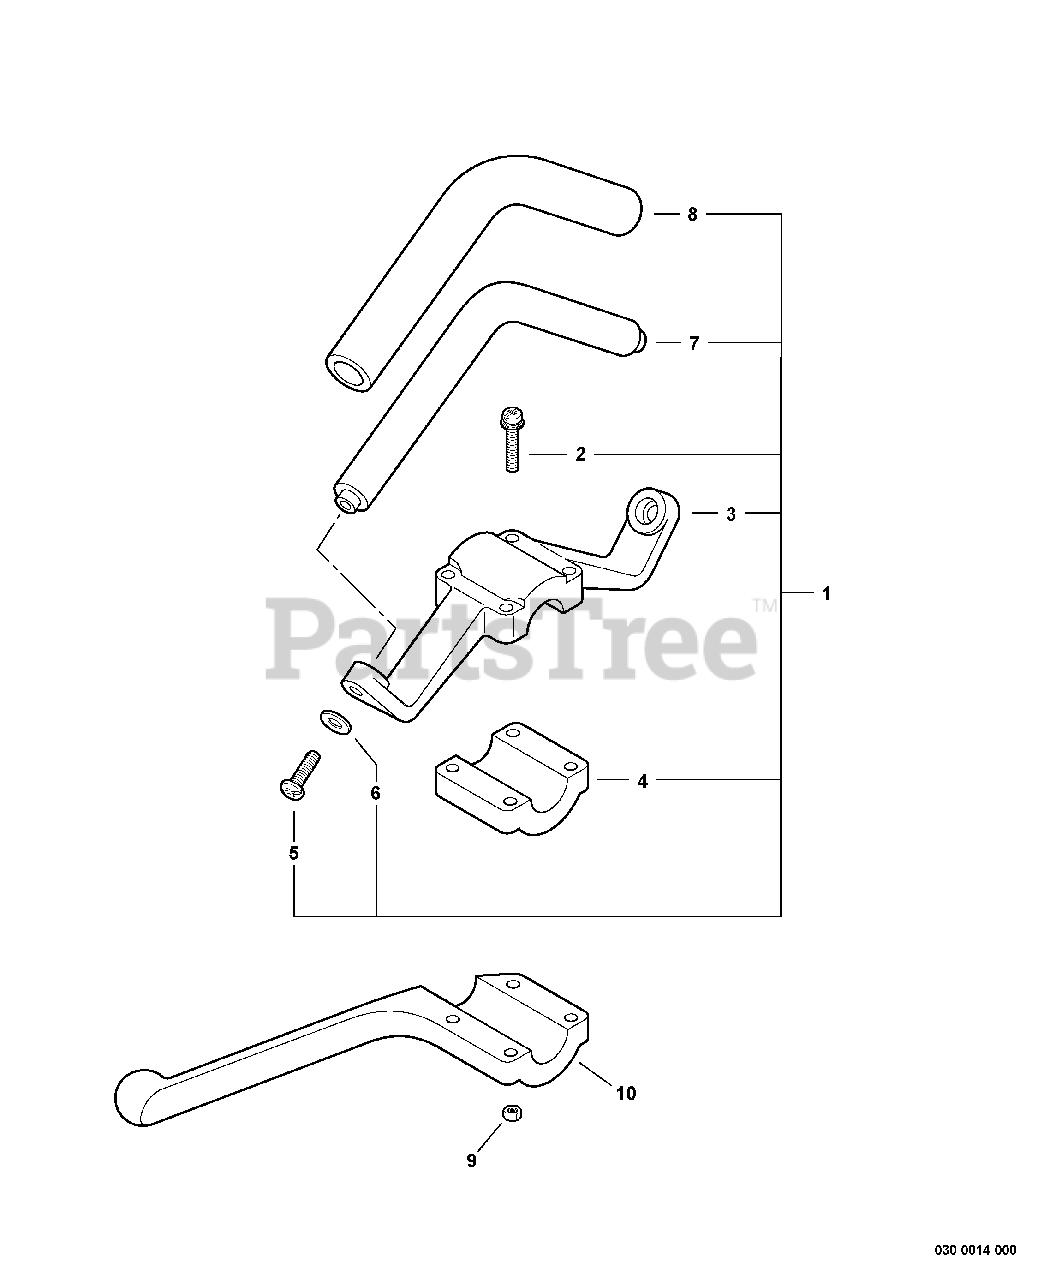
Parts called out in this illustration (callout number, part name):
1	HANDLE ASSY - FRONT
2	SCREW - 5X35
3	BRACKET, HANDLE - UPPER
4	BRACKET, HANDLE - LOWER
5	SCREW - 5X20 -- TAPPING
6	WASHER - 5
7	HANDLE - FRONT
8	GRIP, HANDLE
10	BAR, BARRIER
